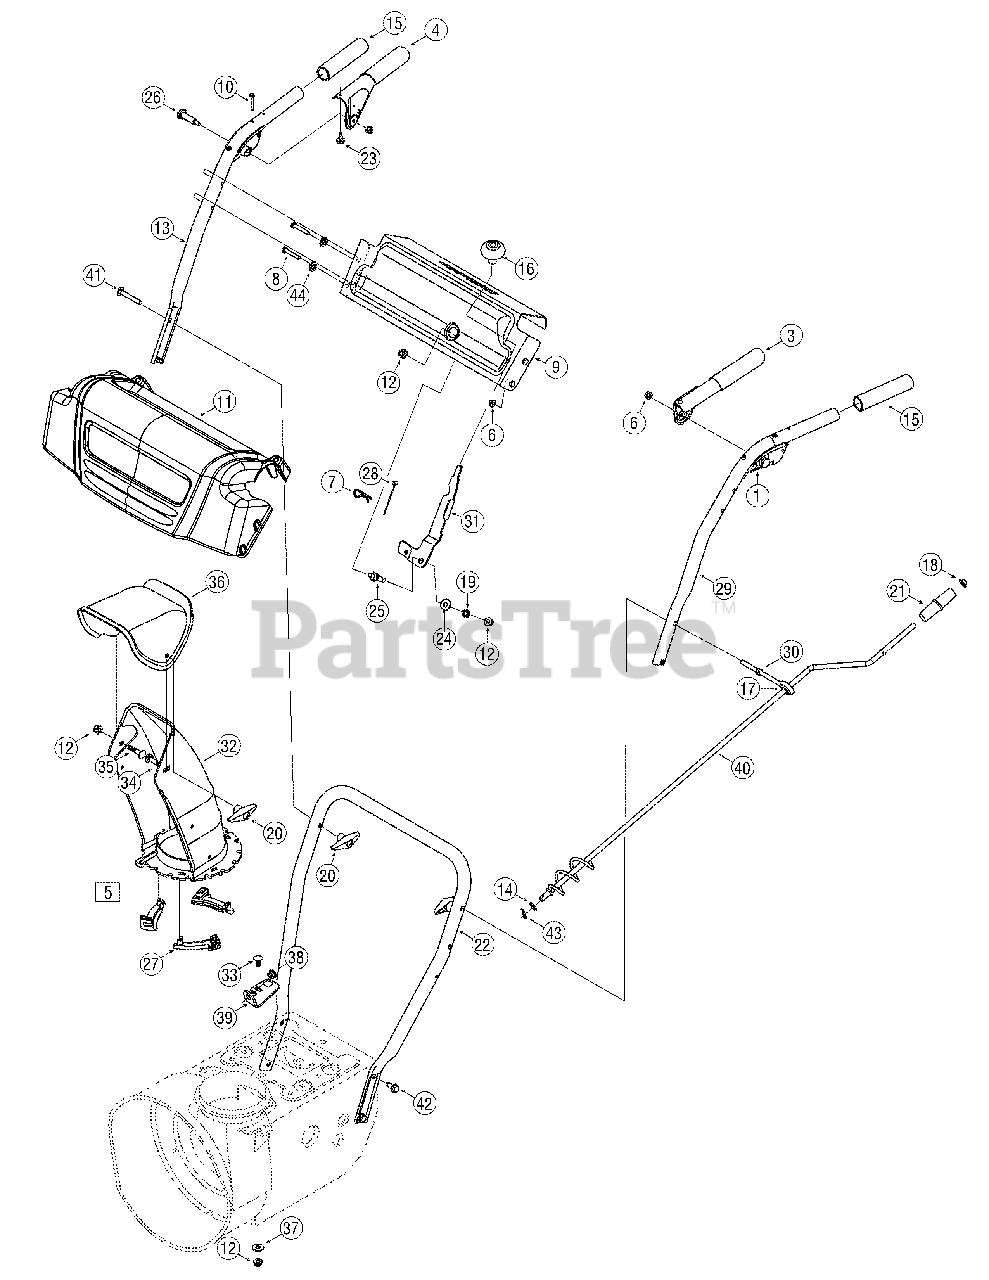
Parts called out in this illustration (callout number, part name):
1	Handle Assembly, Clutch Lock, LH
2	Handle Assembly, Clutch Lock, RH
3	Handle Ass’y, Engage, Black, LH
4	Handle Ass’y, Engage, Black, RH
5	Chute Assembly
6	Nut, Flglk, 1/4-20
7	Click Pin
8	Screw, 1/4-20, 1.75, Gr5
9	Panel, Handle,
10	Screw, Machine, #10-24, 1.375
11	Handle Panel Cover
12	Nut, Flange Lock, 5/16-18, Nylon
13	Handle, Upper, RH
14	Washer, Flat, .375 x .738 x .063
15	Grip, 1.0 ID x 5.0
16	Knob, Shift, Black
17	Grommet, .44 ID x .94 OD x .50
18	Cap, Push, 3/8 Rod
19	Spring, .39 x .60 x .88
20	Knob, 5/16-18, Black
21	Crank Knob, 1.0 Dia. x 3.2, Black
22	Handle, Lower
23	Bumper, Rubber, .62 OD x .22
24	Washer, Flat, .385 x .870 x .092
25	Bolt, Shoulder, 5/16-18 x 0.905
26	Screw, Shoulder, .43 x 1.3, 1/4-20
27	Chute, Flange Keeper
28	Cable, Speed Selector
29	Handle, Upper, LH
30	Eye Bolt, Chute Crank
31	Shift Lever
32	Chute, Lower, 5.0 Dia.
33	Bolt, Carriage, 5/16-18, 1.0
34	Bolt, Carriage, 5/16-18, 1.0
35	Bolt, Carriage, 5/16-18, .750
36	Chute, Upper, w/ Label
37	Washer, .349 x .879 x .063
38	Bushing, Plastic, .380
39	Bracket, Chute Crank
40	Crank Assembly, Chute
41	Screw, Carriage, 5/16-18, 2.25
42	Screw, 5/16-18, 2.25, Gr5
43	Pin, Cotter, .072 x 1.13
44	Washer, Flat, .25 x .630 x .0515
